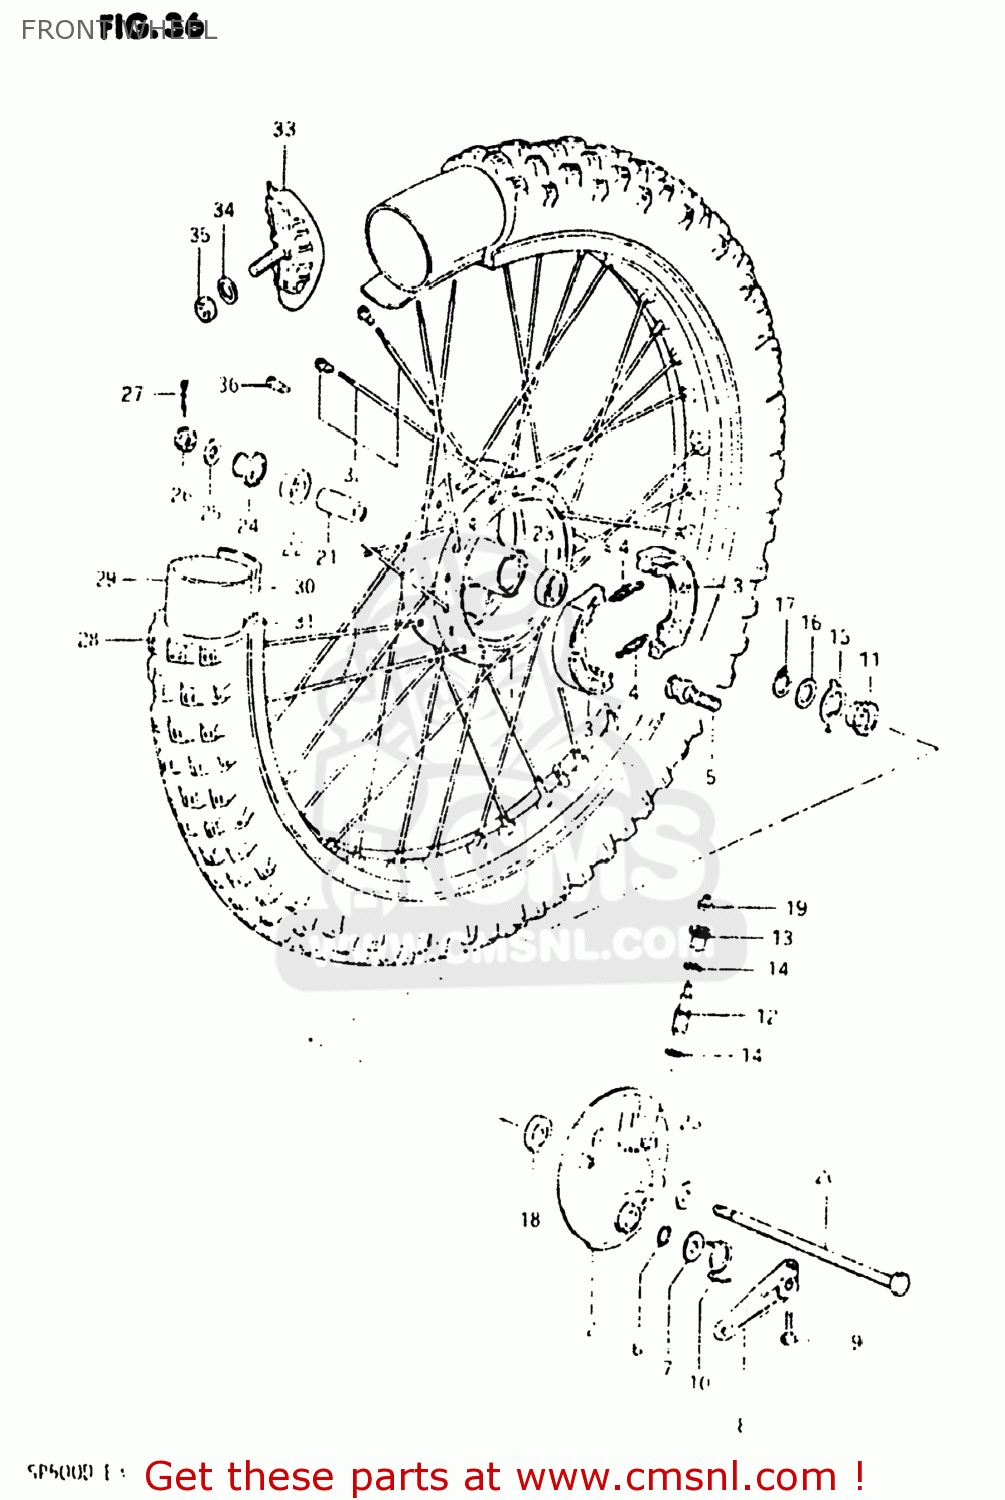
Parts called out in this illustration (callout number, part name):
1	DRUM,FRONT HUB
2	PANEL,FRONT BRAKE
3	SHOE,BRAKE
4	SPRING
5	CAM,FRONT BRAKE
6	O-RING,BOSS
7	WASHER (15X24X1.6)
8	LEVER,FRONT BRAKE CAM
9	BOLT
10	SPRING
11	GEAR,SPEEDOMETER
12	PINION,SPEEDOMETER
13	BUSHING,SPEEDOMETER PINION
14	WASHER (5.1X9X0.4)
15	DRIVER,SPEEDOMETER GEAR
16	WASHER(22.5X27X1)
17	CIRCLIP
18	SEAL,OIL(26X38X4)
19	SEAL,OIL(6X10X3)
20	AXLE,REAR
21	SPACER (12.6X19X52)
22	BEARING, RH
23	BEARING
24	SPACER,FRONT AXLE,RIGHT
25	WASHER
26	NUT, REAR AXLE
27	COTTER PIN
28	TIRE 3.00-21
29	TUBE
30	PROTECTOR,WHEEL,INNER
31	RIM,FRONT WHEEL (1.60X21)(
32	SPOKE SET,FRONT
33	STOPPER,BEAD
34	WASHER
35	NUT
36	BALANCER,WHEEL (50G)
